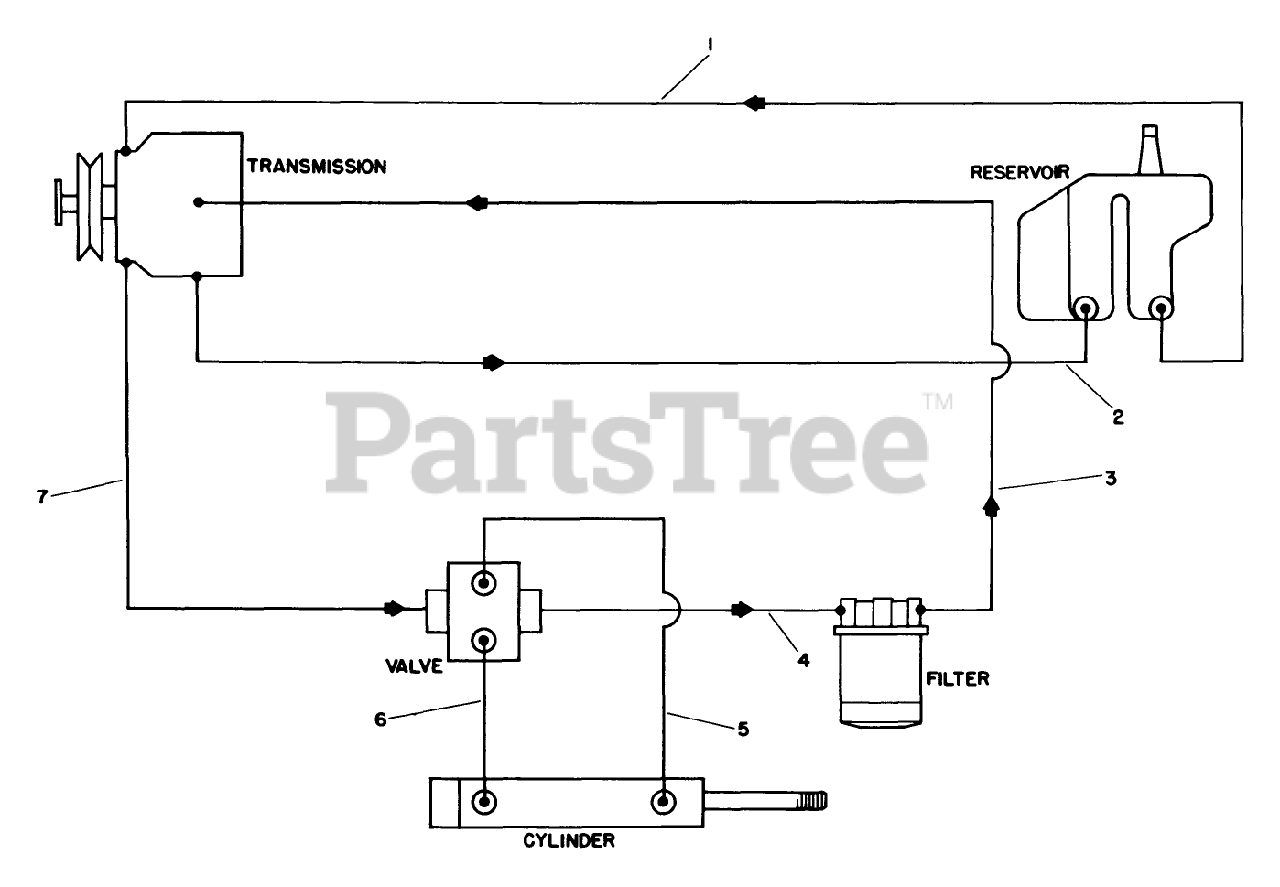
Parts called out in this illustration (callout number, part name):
1	HOSE ASM
2	TUBE ASM
3	HOSE ASM
4	HOSE ASM
5	HOSE ASM
6	HOSE ASM
7	HOSE ASM
